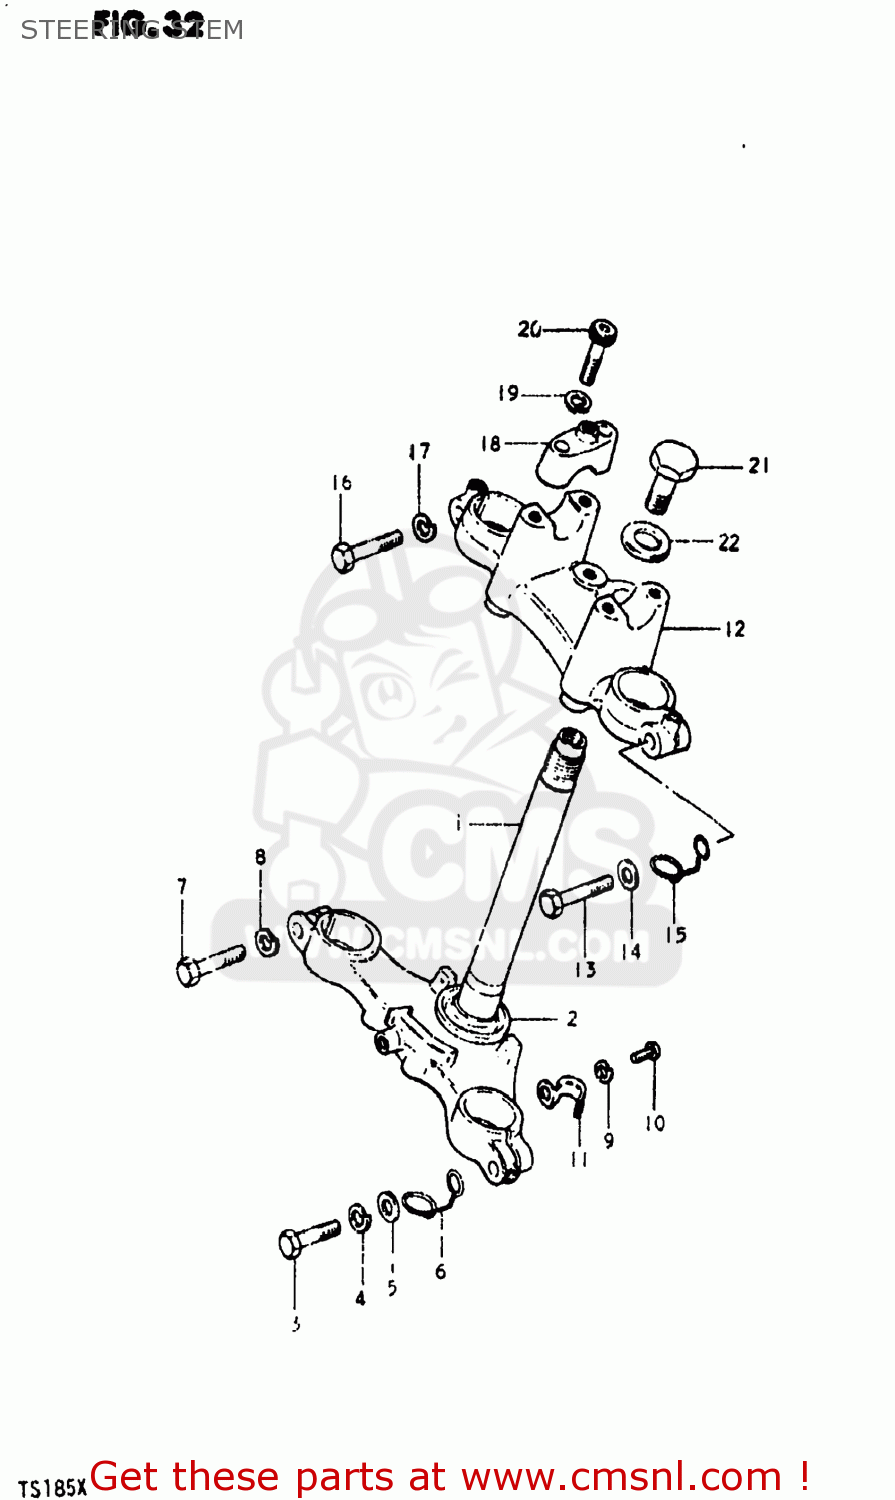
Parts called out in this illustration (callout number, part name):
1	STEM,STEERING
2	RACE,STEERING OUTER LWR
3	BOLT 12X45
4	WASHER,LOCK 12
5	WASHER
6	CLIP
7	BOLT
8	WASHER,LOCK 12
9	LOCK WASHER
10	SCREW
11	CLIP,BRAKE CABLE
12	HEAD,STEERING STEM
13	BOLT 10X40
14	WASHER
15	CLIP
16	BOLT 10X40
17	LOCK WASHER
18	HOLDER,HANDLEBAR(GOLD)
19	LOCK WASHER
20	BOLT 8X35
21	BOLT,FORK INNER TUBE
22	WASHER,STEM HEAD(10.5X30X3.2)
